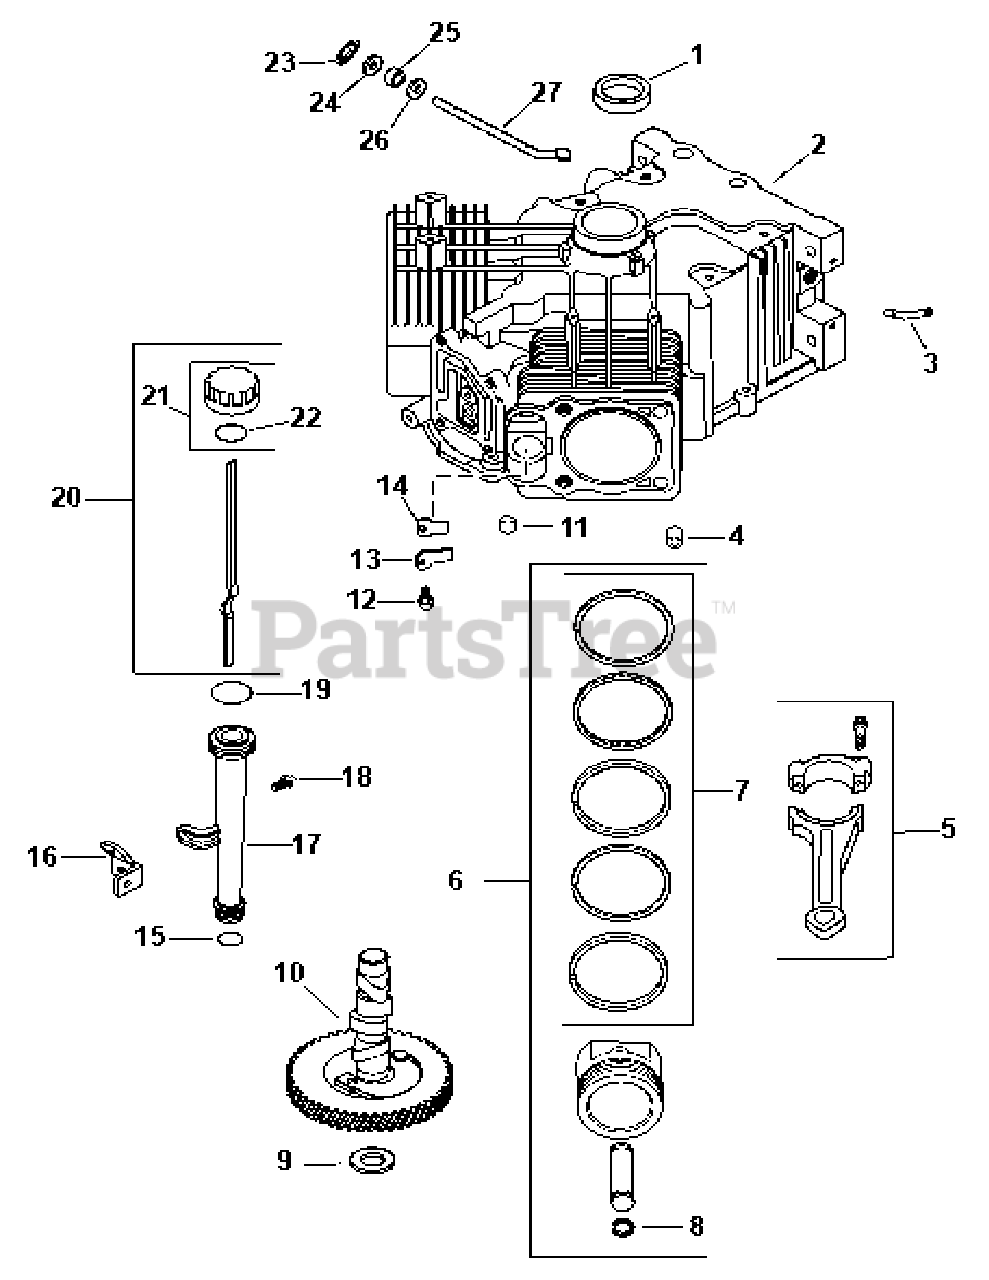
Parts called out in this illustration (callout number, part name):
1	Oil Seal
4	Split Dowel Pin
5	Connecting Rod (Std.)
5	Connecting Rod (.25)
6	Piston w/Ring Set Kit (Std.)
6	Piston w/Ring Set Kit (.08)
6	Piston w/Ring Set Kit (.25)
6	Piston w/Ring Set Kit (.50)
7	Ring Set (Std.&.08)
7	Ring Set (.25)
7	Ring Set (.50)
8	Piston Pin Retainer
9	Shim (White)
9	Shim (Blue)
9	Shim (Red)
9	Shim (Yellow)
9	Shim (Green)
9	Shim (Gray)
9	Shim (Black)
10	Camshaft Kit
11	Plug
13	Reed Retainer
14	Breather Reed
15	O-Ring
16	Oil Fill Tube Bracket
17	Oil Fill Tube
18	Screw
21	Oil Fill Cap Kit
22	O-Ring Dipstick
23	Ring Retainer
24	9mm Flat Washer
25	Oil Governor Shaft Seal
27	Governor Cross Shaft
